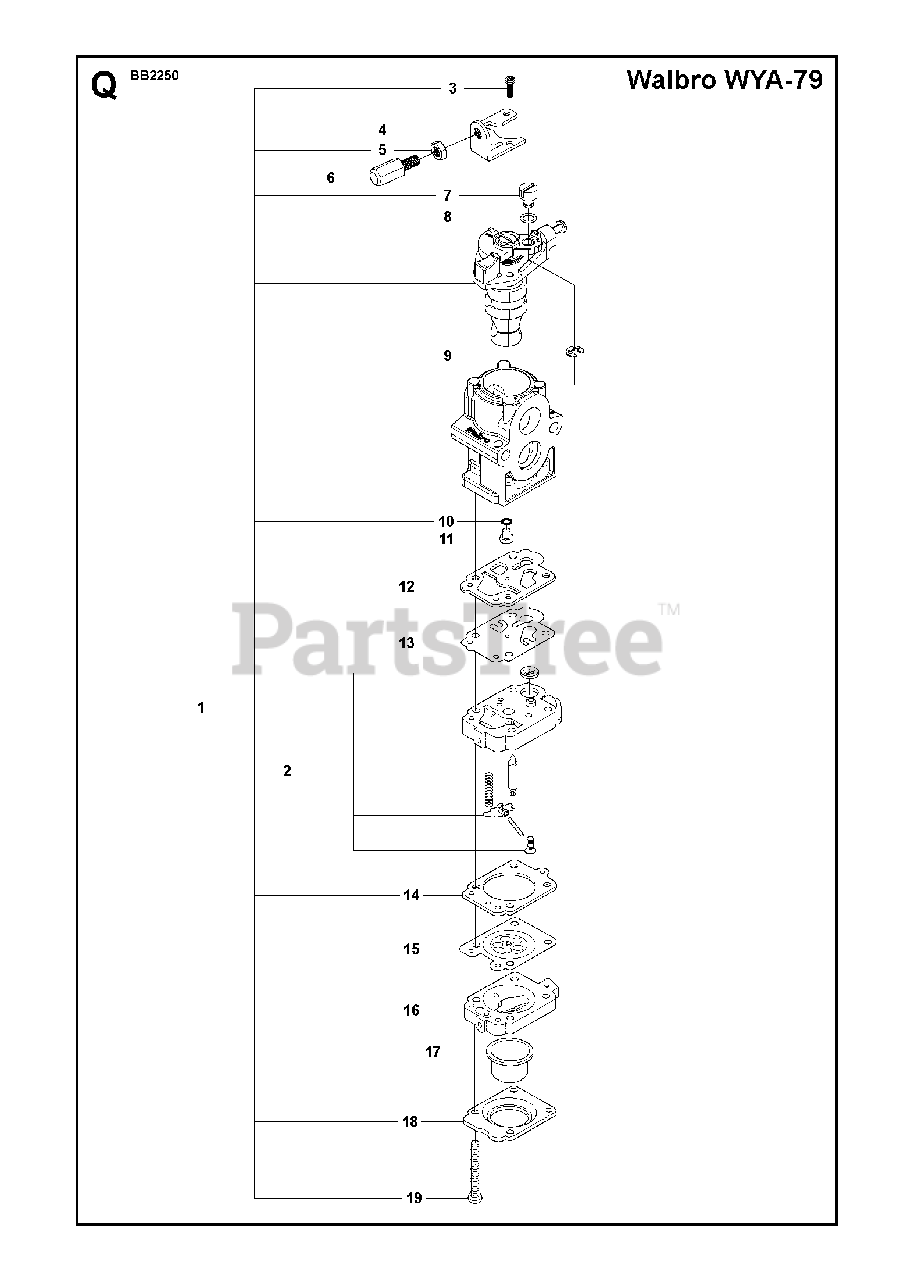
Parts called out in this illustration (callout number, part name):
1	CARBURETOR
2	RP_BODY-A-PUMP
3	SCREW
4	RP_BRACKET
5	NUT
6	SCREW
7	SWIVEL
8	WASHER
9	RING
10	O-RING
11	JET
12	GASKET
13	DIAPHRAGM
14	GASKET
15	DIAPHRAM
16	BODY
17	PUMP
18	COVER
19	SCREW
